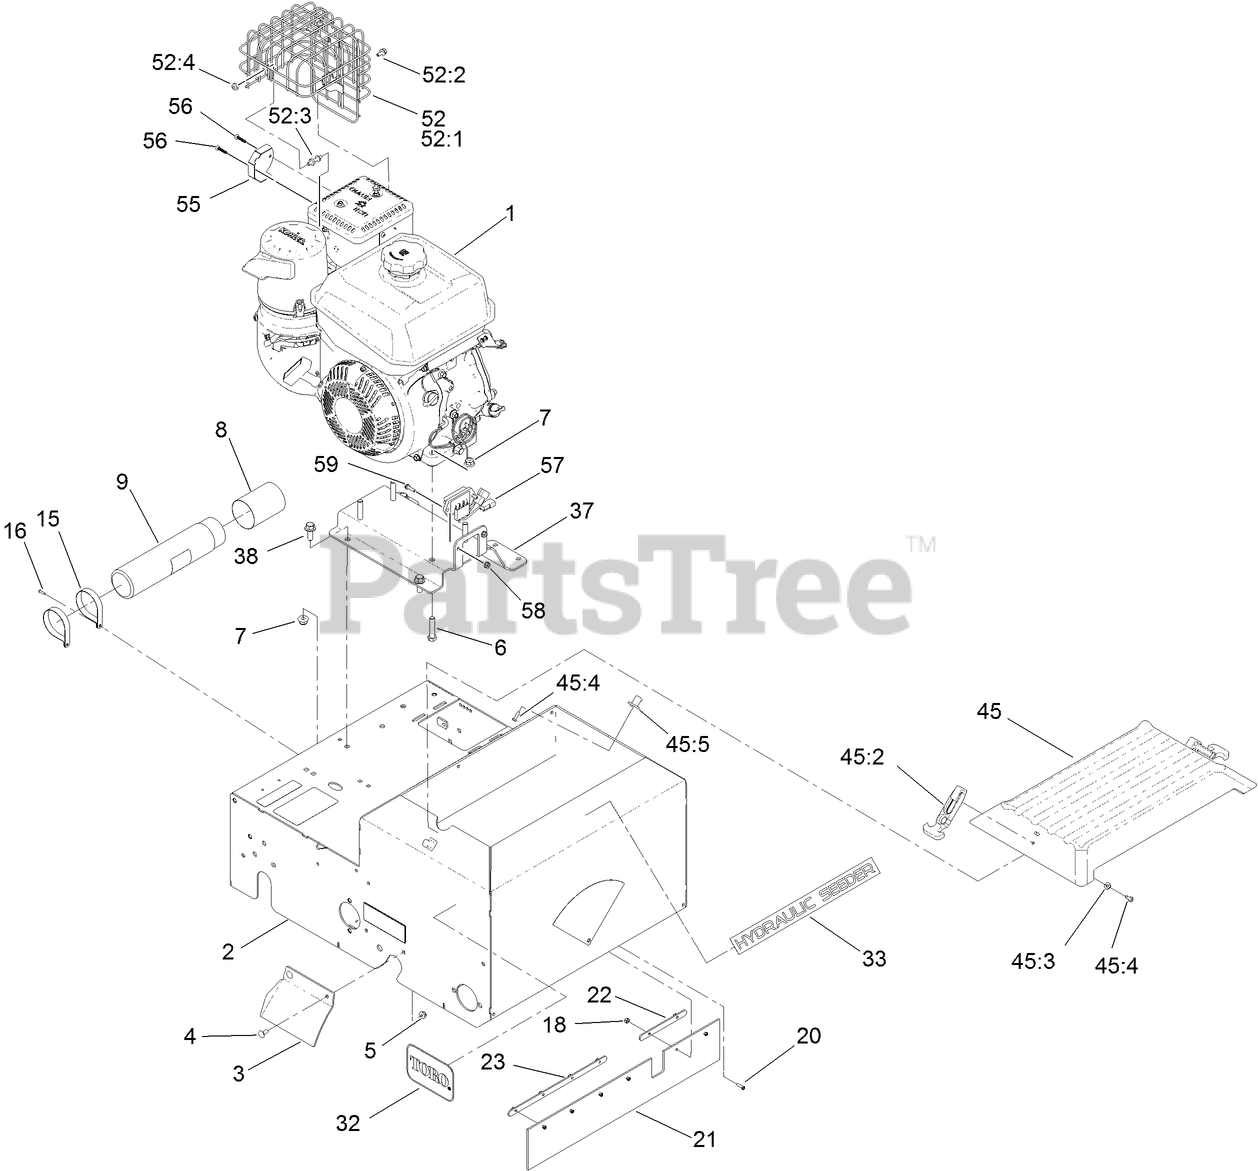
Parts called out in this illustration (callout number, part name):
2	FRAME ASM
3	GUARD-RH
4	SCREW-CARR
5	NUT-HF
6	SCREW-HH
7	NUT-HF, NI
8	CAP-HOUSING
9	TUBE-MANUAL
15	CLAMP-R
16	RIVET-POP
18	NUT-LOCK
20	SCREW-SHH
21	GUARD-DUST
22	PLATE-RETAINER
23	PLATE-RETAINER
32	DECAL
37	PLATE-ENGINE
38	SCREW-HHF
45	SEEDER COVER KIT
45:2	LATCH-RUBBER
45:3	WASHER-FLAT
45:4	SCREW-PPH
45:5	LATCH-KEEPER
52	GUARD-MUFFLER
55	DEFLECTOR-EXHAUST
56	SCREW-PPH
57	REGULATOR
58	NUT-LOCK, FLANGE
59	SCREW-HWH
